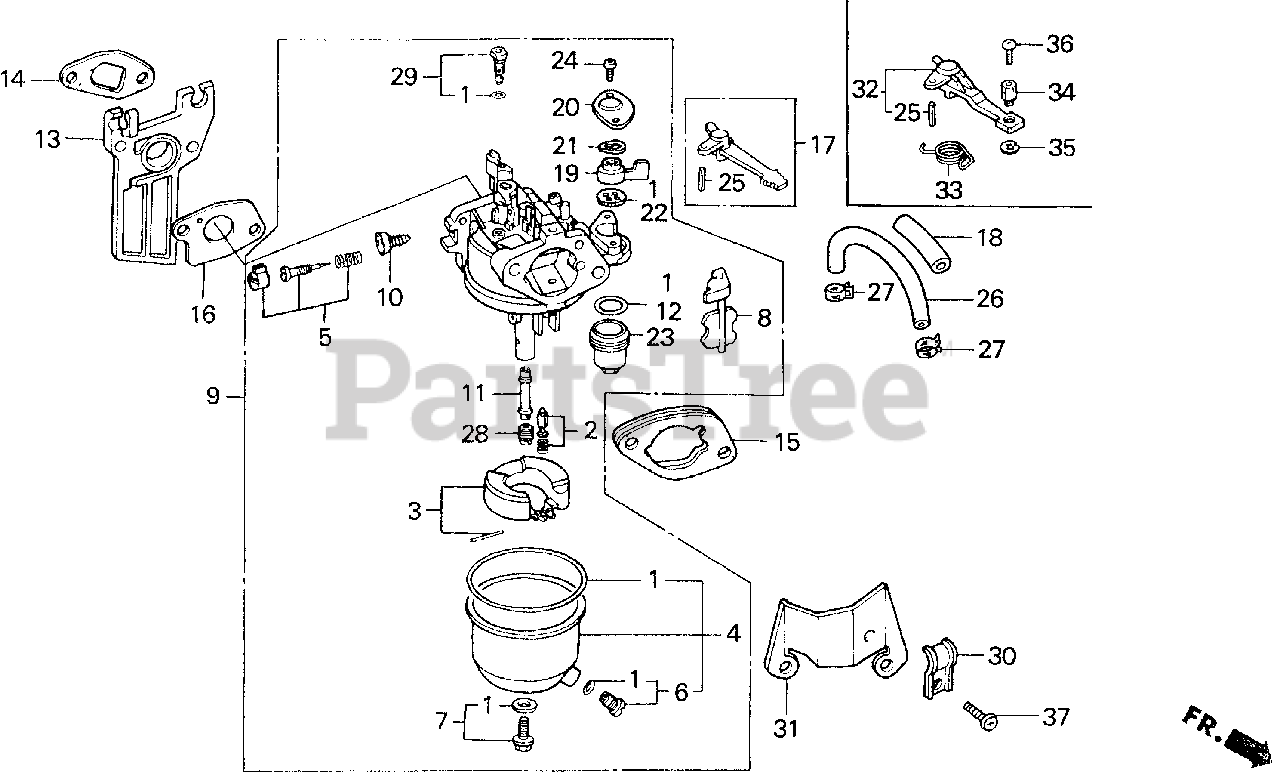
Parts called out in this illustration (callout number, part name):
1	GASKET SET
2	VALVE SET, FLOAT
3	FLOAT SET
4	CHAMBER SET, FLOAT
5	SCREW SET
6	SCREW SET, DRAIN
7	SCREW SET B
8	CHOKE SET
9	CARBURETOR ASSY. (BE65B B)
10	SCREW, THROTTLE STOP
11	NOZZLE, MAIN
12	GASKET, FUEL STRAINER CUP
13	INSULATOR, CARBURETOR
14	GASKET, INSULATOR
15	SPACER, CARBURETOR
16	GASKET, CARBURETOR
17	LEVER, CHOKE (STD)
19	LEVER, VALVE
20	PLATE, LEVER SETTING
21	SPRING, VALVE LEVER
22	GASKET, VALVE
23	CUP, FUEL STRAINER
24	SCREW, PAN (3X6)
24	SCREW, PAN (3X8)
25	PIN, SPRING (2X12)
28	JET, MAIN (#65)
28	JET, MAIN (#68)
28	JET, MAIN (#70)
29	JET SET, PILOT (#35)
